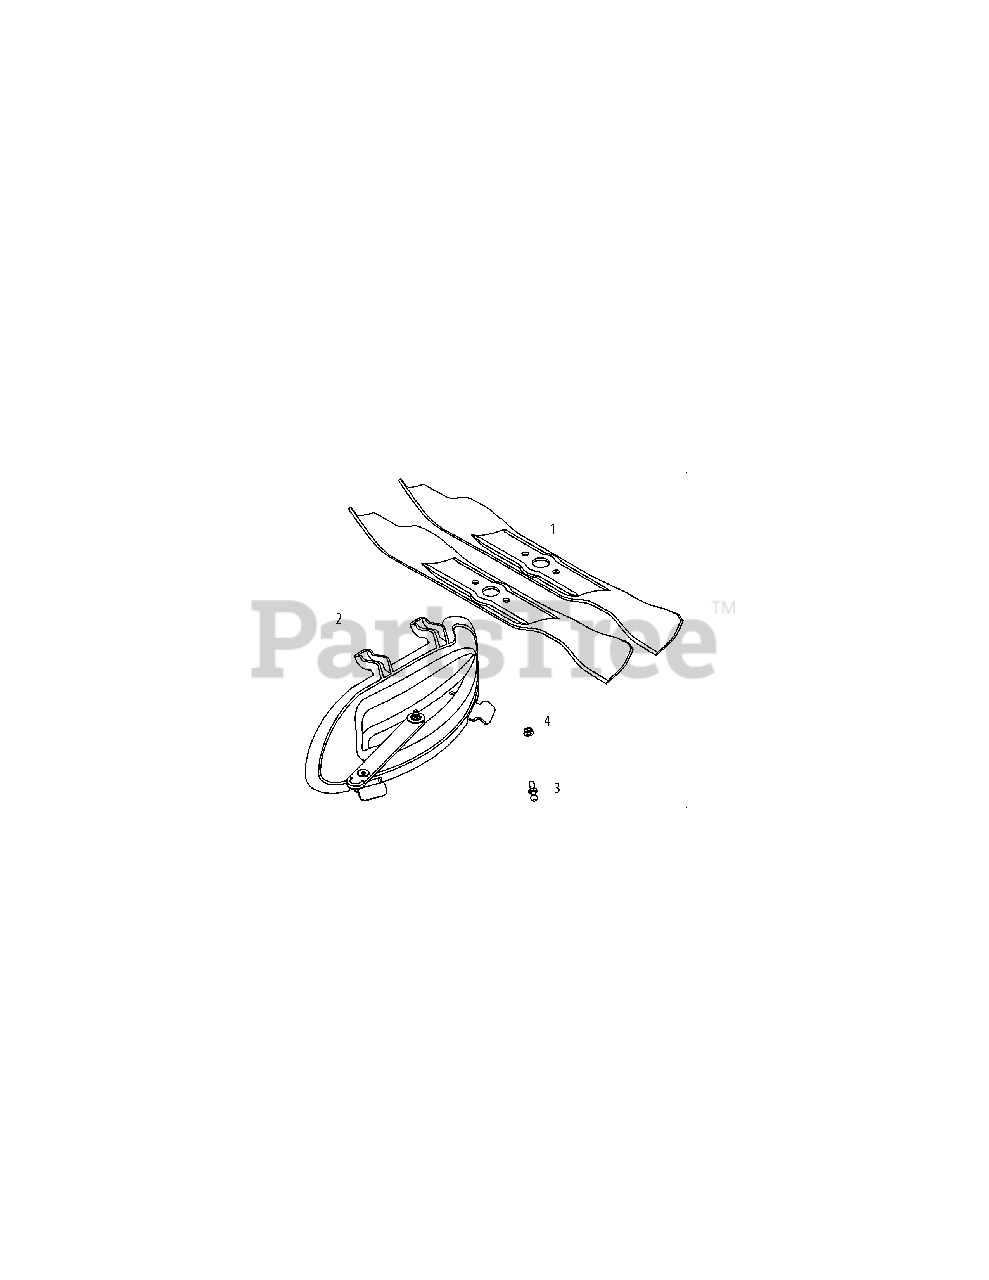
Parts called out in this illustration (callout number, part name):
1	Blade, 21.20
2	Plug, Mulch Assy 42"
3	Pin, Grasscatcher
4	Nut, Flange
